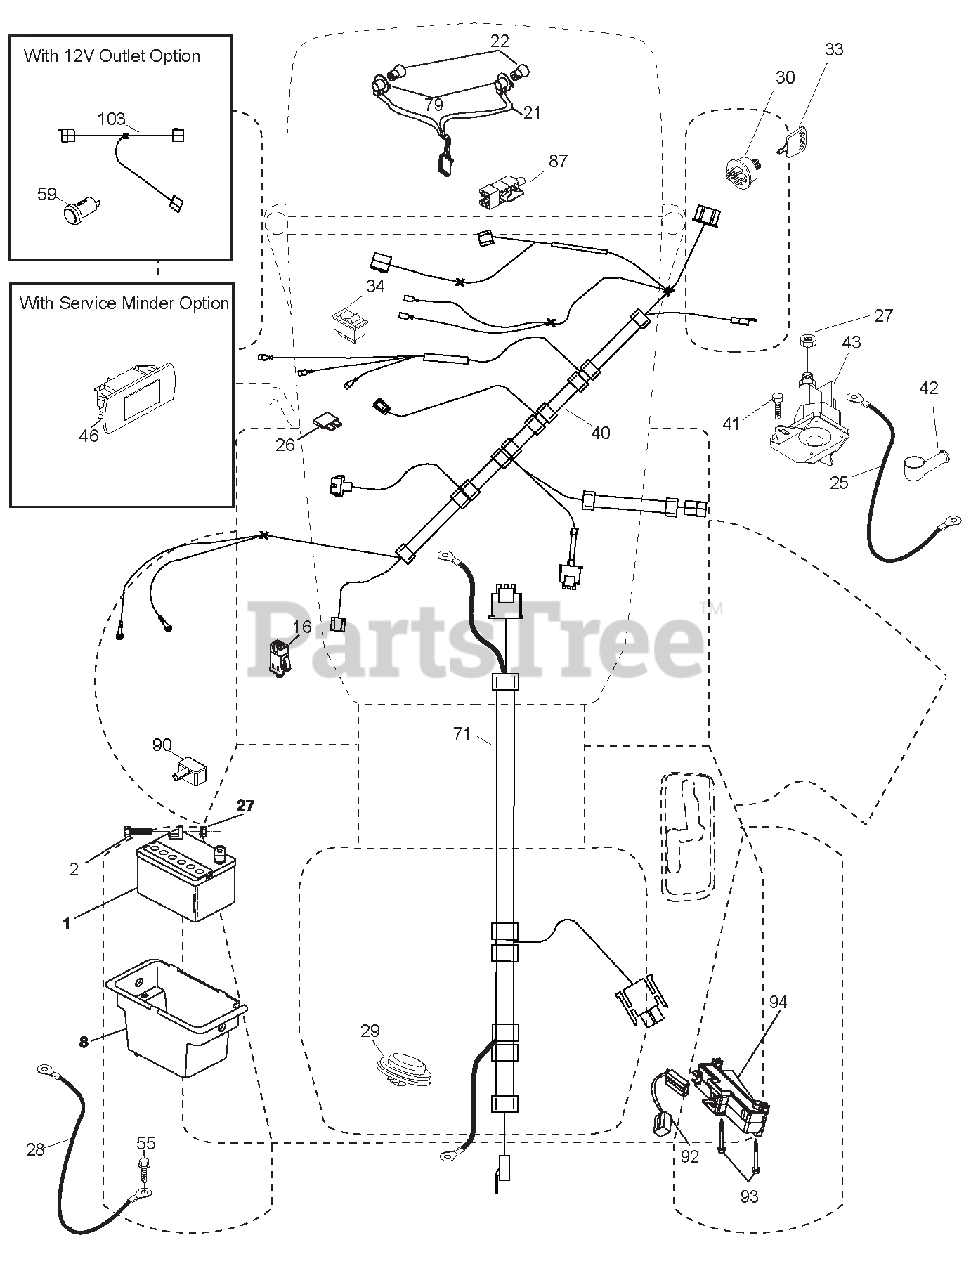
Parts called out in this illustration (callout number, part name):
1	BATTERY.12.VOLT.28.AMP.WET
2	BOLT.HEX.HD.1/4-20UNC X 3/4
8	BOX.BATTERY.MNT.REAR.LT.TEX.BL
16	SWITCH.INTERLOCK.NONO.GRAY
21	HARNESS ASM.LIGHT.22"(4152J)
22	BULB.LIGHT.#1156
25	CABLE.STARTER.6GA.BL/RED.14.5"
26	FUSE.20 AMP.
27	Nut, Keps Hex 1/4-20 unc
28	CABLE.BLACK.22"REAR BATT.TEX
29	SWITCH.SEAT.DELTA.OPC.9LB.
30	SWITCH.IGN.DLTA.P-IN.ROS
33	KEY/CHAIN.BLISTER PACK.GEN.USA
34	SWITCH.LIGHT/RESET.B/B/RED.
40	HARNESS.IGN.DASH.CBL.YTGT.PRED
41	Screw 1/4-20 x 1/2
42	COVER.TERMINAL.RED
43	SOLENOID.W/BRASS PLUNGER.2005
55	SCREW.5/16-18X3/4.SMGML.TAP/R
71	HARNESS.IGN.CHASS.TEX.REAR.BAT
79	SOCKET ASM.BULB.TWISTLOCK
87	SWITCH.INTRLCK.CLUTCH.CABLE.TX
90	COVER TERMINAL BATTERY FR. TEX
92	HARNESS.PIGTAIL.CONSLE.ROS.MLK
93	SCREW.PLASTITE.10-14 X 2.0
94	MODUAL REVERSE ROS
